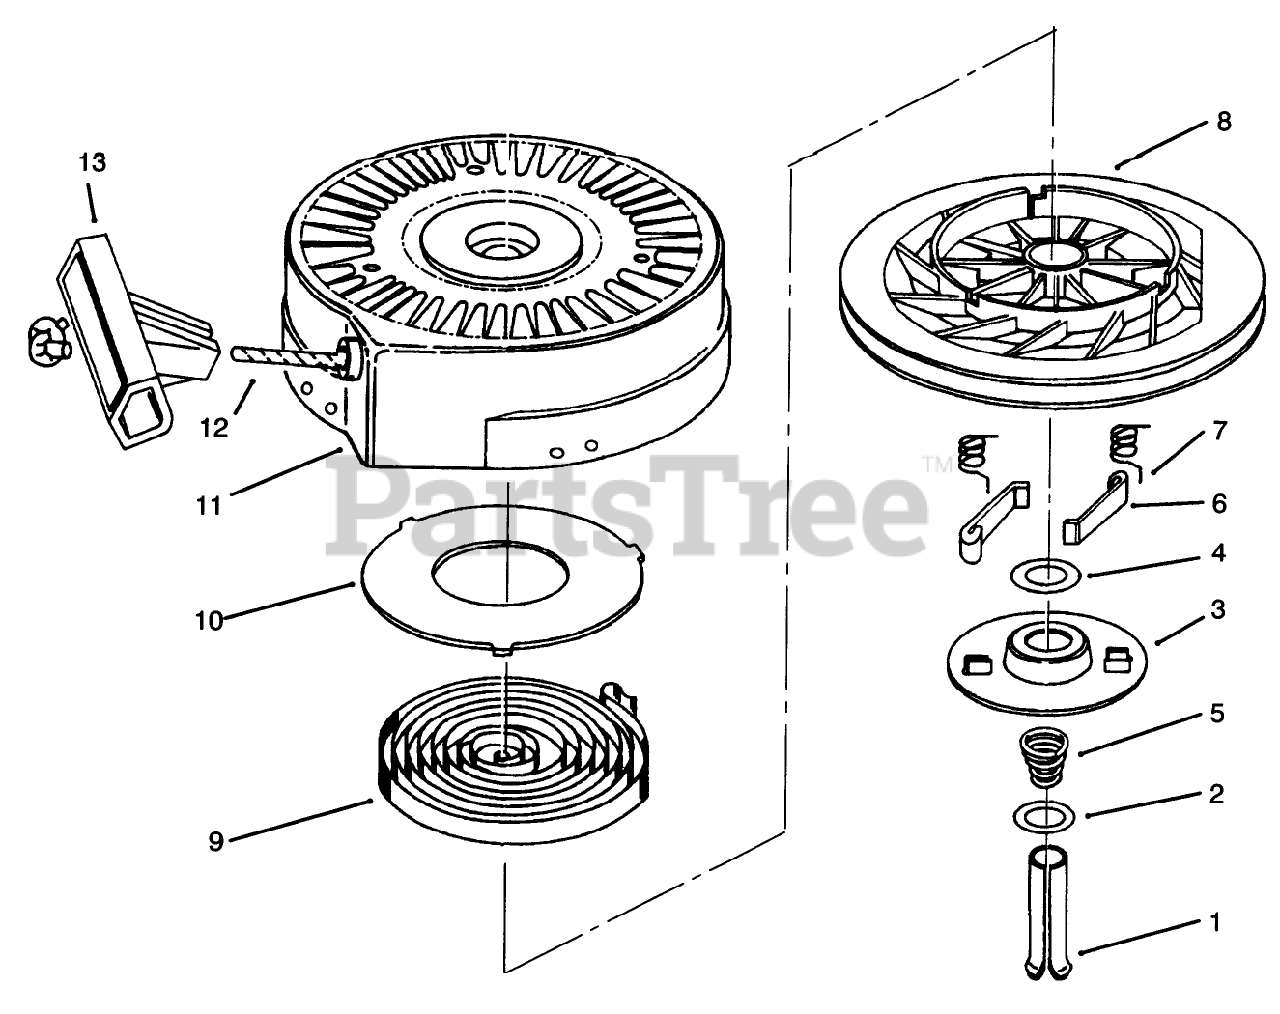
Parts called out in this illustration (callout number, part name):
1	Pin, Spring (Incl. Ref. #7)
2	Washer
3	Retainer
4	Washer
5	Brake Spring
6	Dog-Starter
7	Spring-Dog
8	Pulley
9	Rewind Spring
10	Cover-Spring
11	Starter Housing ASM
12	Rope-Starter (98 cut to length)
13	Handle-Starter
